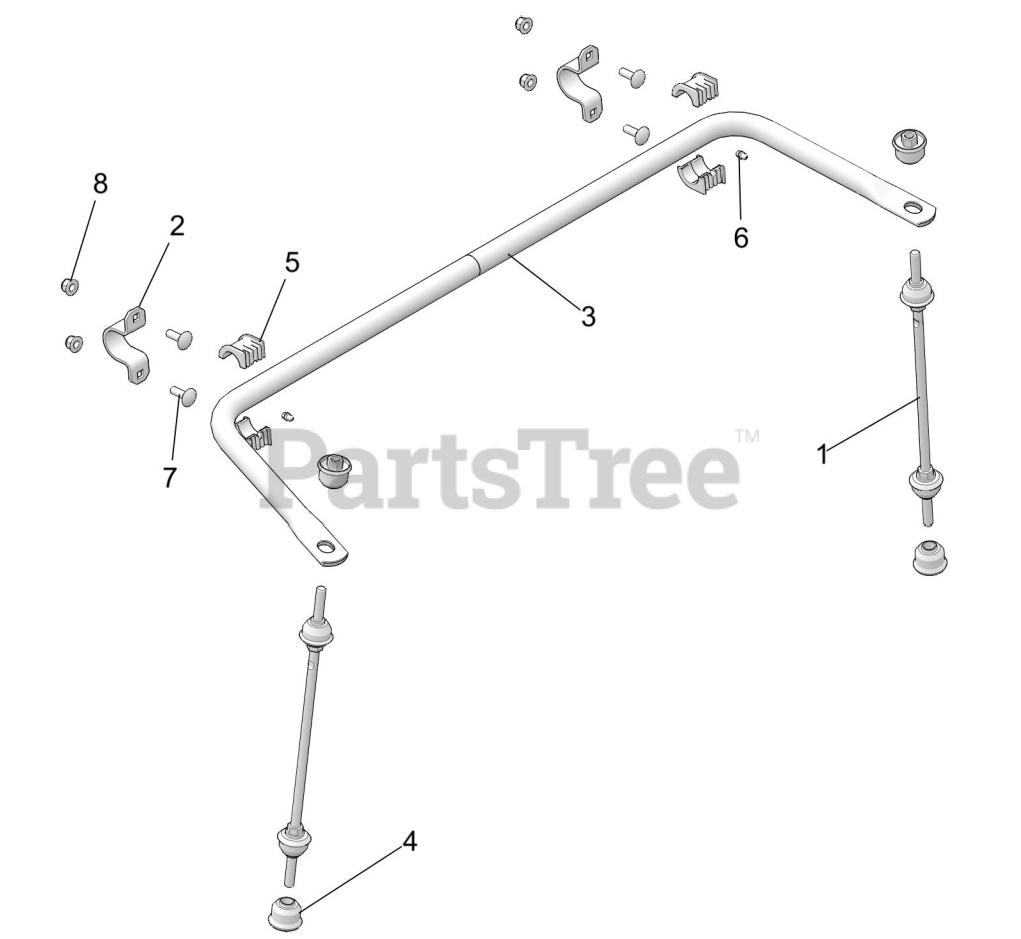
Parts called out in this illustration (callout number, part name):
1	ASM-LINKAGE,STABILIZER BAR
2	BRKT-BUSHING
3	TUBE-STABILIZER,M.BLK
4	BUSHING-LNKG TORBAR,DURO80
5	BUSHING-REAR STABILIZER
6	FITTING-LUB,1/4-28-STR/1792-Y
7	SCR-RHCAR-M8X1.25X25 10.9 ZB3
8	NUT-M8X1.25,FLG,NYLOC-OLIVE D
